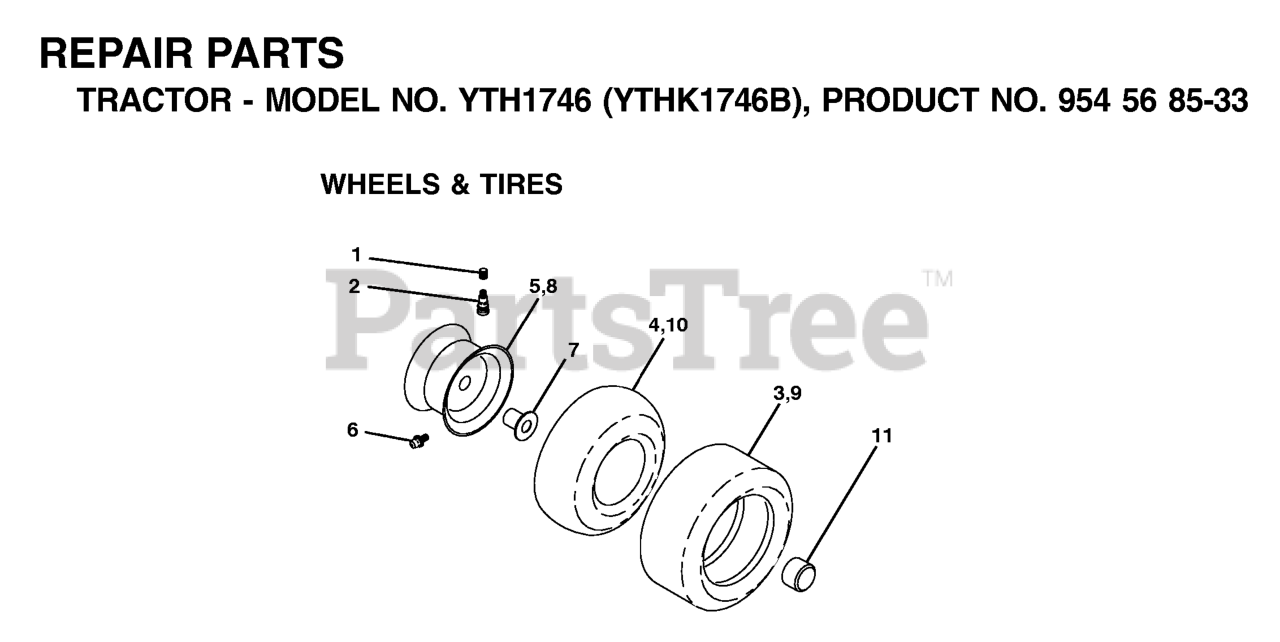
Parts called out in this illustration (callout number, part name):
1	SEAT - GREY
2	BRKT.PIVOT.FENDER
3	STRAP
6	NUT
7	SPRING COMPRESSION
8	BOLT.5/16-18UNCX3/4 W/SEMS.BLK
10	PAN.ASM.SEAT.3PT
21	BOLT.SHOULDER.5/16-18
37	NUT.71038.31-18.HEX.NYLOCK
40	HANDLE.SLIDE.SEAT.TEX.BLACK
41	SPRING.LATCH.SEAT.TEX
44	WASHER 13/32 X 2-3/8 X 12GA
